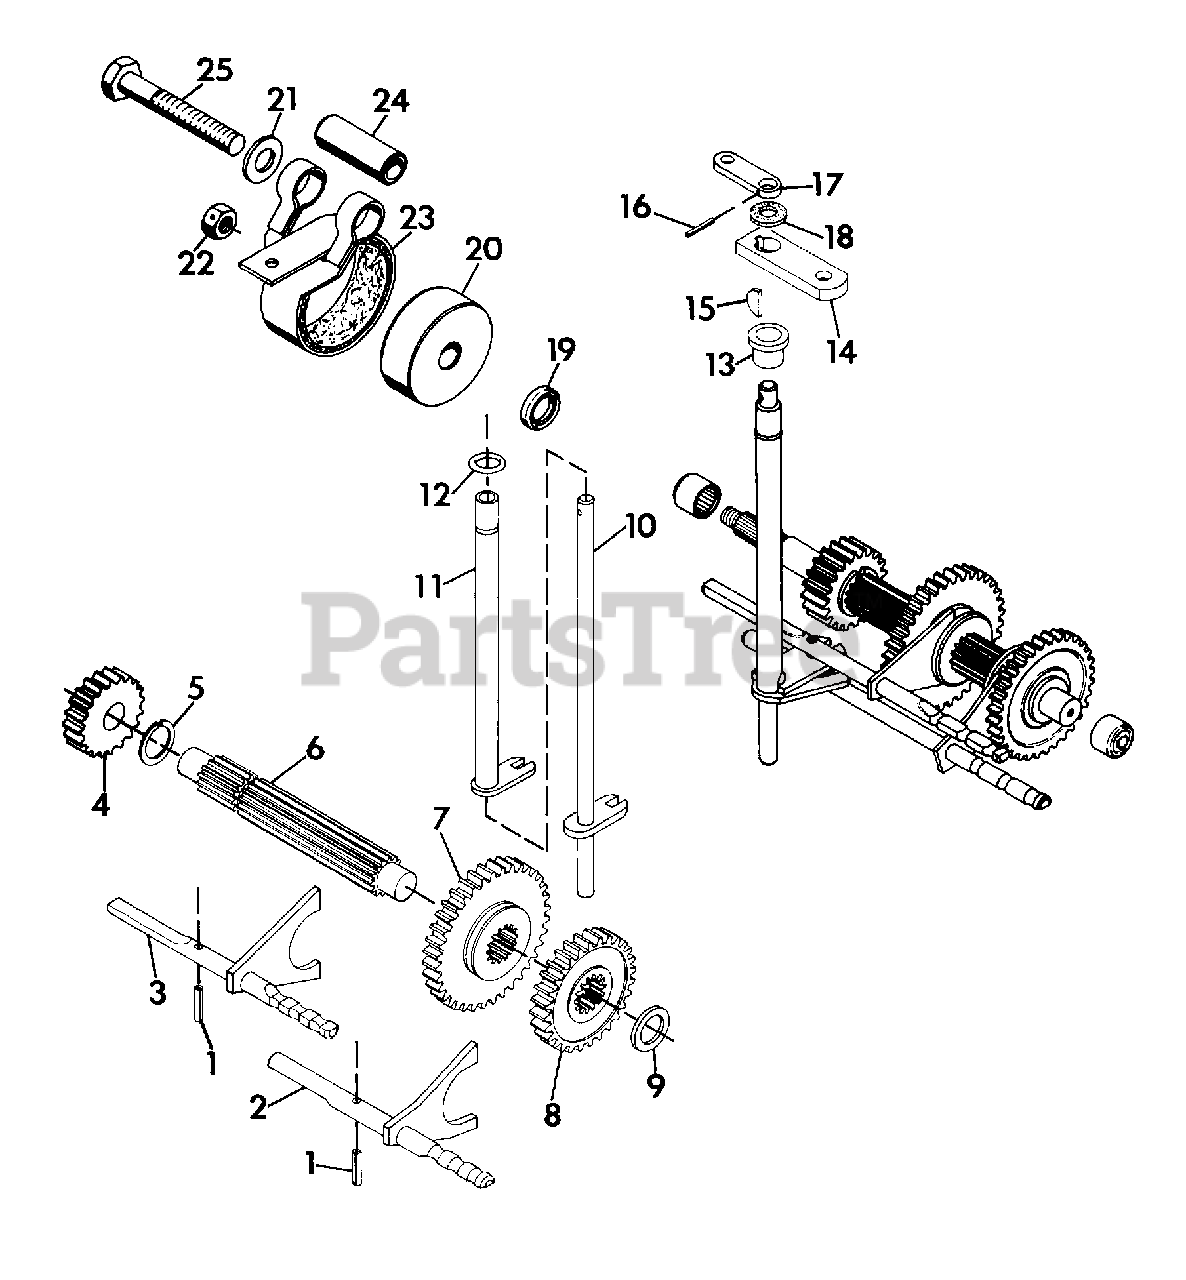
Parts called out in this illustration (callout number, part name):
1	PIN, SPRING .25X.75
2	WELDMENT, RAIL SHIFT FORK 2&4 RANGE
3	WELDMENT, RAIL SHIFT FORK 1&3 RANGE
4	GEAR, 8 DP 16 TEETH X .850
5	RING, RETAINING 1.00 SHAFT
6	SHAFT, SLIDE GEAR
7	GEAR, SLIDING 10 DP 36 TEETH X .594
8	GEAR, SLIDING 10 DP 30 TEETH X .594
9	RACE, BEARING THRUST .752X1.240X.095
10	WELDMENT, 2ND AND 4TH SHIFTER
11	WELDMENT, 1ST AND 3RD SHIFTER
12	O-RING, 5/8X3/4X1/16
13	BUSHING, .756X1.125X.75
14	ARM, SHIFTER
15	KEY, WOODRUFF .125X.375 HARD
16	PIN, SPRING .188X1.0
17	ARM, SHIFTER
18	WASHER, FELT(SPECIAL FOR TRANS.)
19	SEAL, OIL .750X1.254X.188
20	DRUM, BRAKE
21	WASHER, FLAT .531X1.062X.095
22	NUT, LOCK 5/8-11
23	ASSEMBLY, BRAKE BAND
24	BUSHING, .530X.750X2.06
25	BOLT, HEX 1/2-13X2.75
